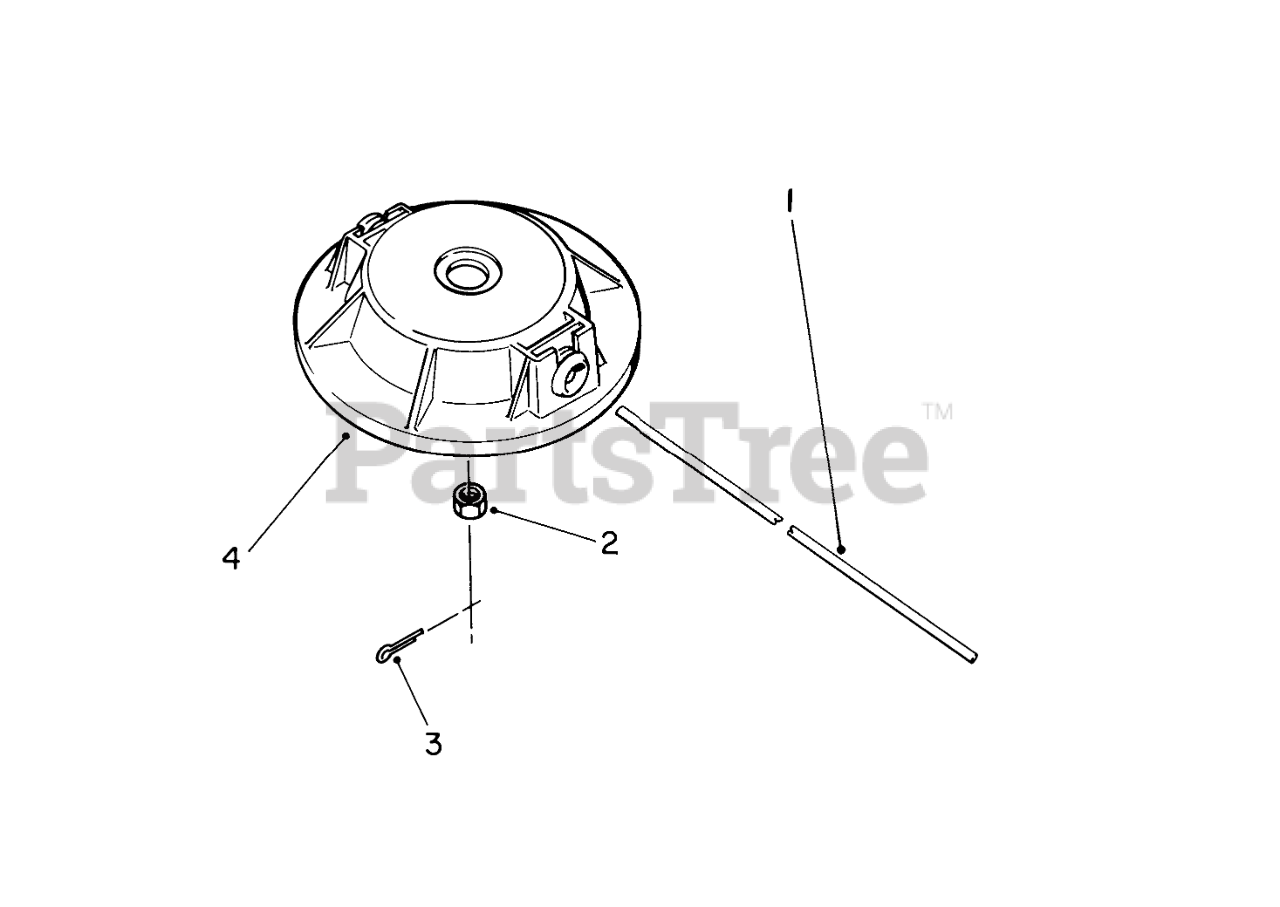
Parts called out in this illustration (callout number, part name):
1	LINE PACK (100)
3	PIN-COTTER
4	CUTTER HEAD-PLASTIC
